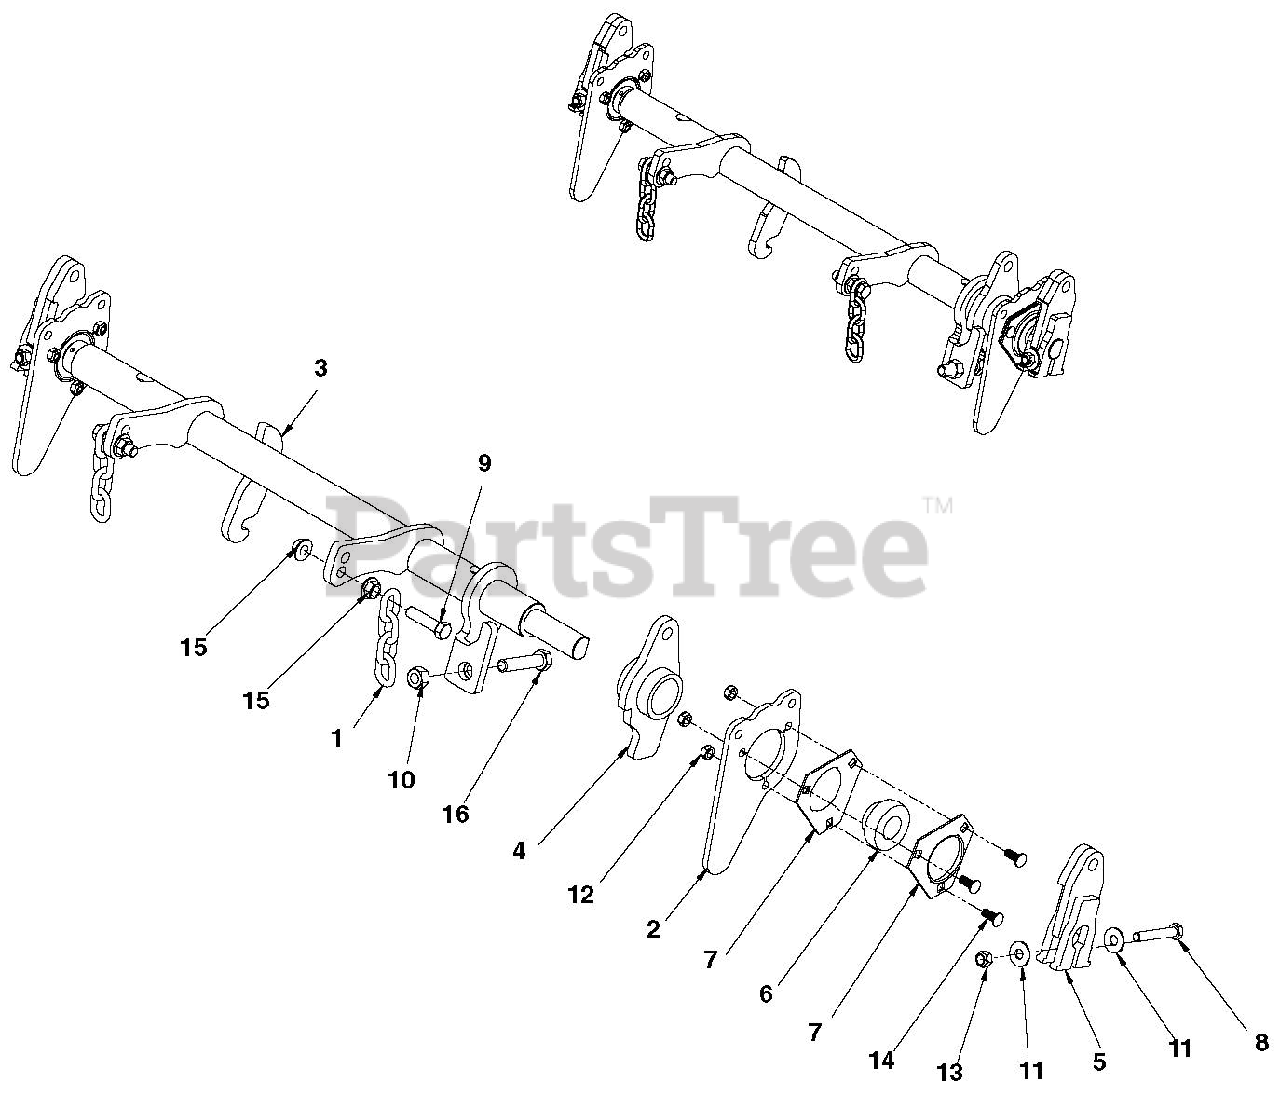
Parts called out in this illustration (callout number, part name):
1	CHAIN, 4 LINKS 1/4" GR70 Y
2	BALL BEARING PLATE
3	WLDT, CENTER LIFT
4	WLDT, HOC ROTATION ADJUSTMENT
5	WLDT, FRONT PIVOT CLAMP
6	BEARING, SET SCREW COLLAR
7	FLANGE, BEARING 52MM-3T-YZP
8	BOLT, 3/8-16X2.25 HEX 5 Y
9	BOLT, 7/16-14X1.75 HEX 5 Y
10	NUT, 1/2-13 STD HEX GR5 Y
11	WASHER, .375 REG FLAT Y
12	LOCKNUT, 5/16-18 CROWN Y
13	LOCKNUT, 3/8-16 CROWN Y
14	BOLT, 5/16-18X.750 CRG 5 Y
15	LOCKNUT, 7/16-14 WHIZ Y
16	BOLT, 1/2-13X2.25 HEX 5 FLTD Y
